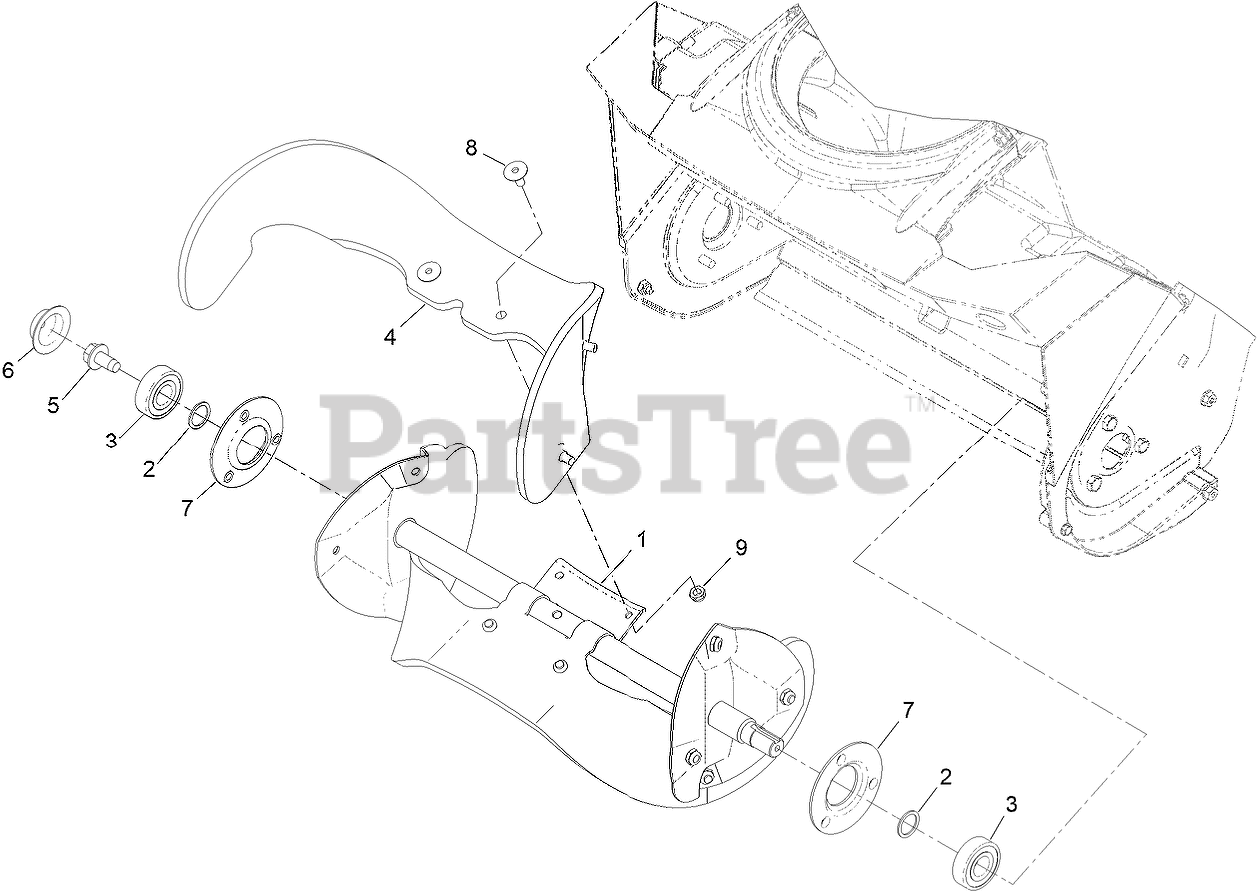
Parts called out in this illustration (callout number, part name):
1	ROTOR ASM
2	WASHER-THRUST
3	BEARING-BALL
4	BLADE-ROTOR
5	SCREW-HWH
6	CAP-SIDEPLATE, RH
7	FLANGE-BEARING
8	SCREW-COUNTERSUNK, OVAL
9	NUT-HEX
